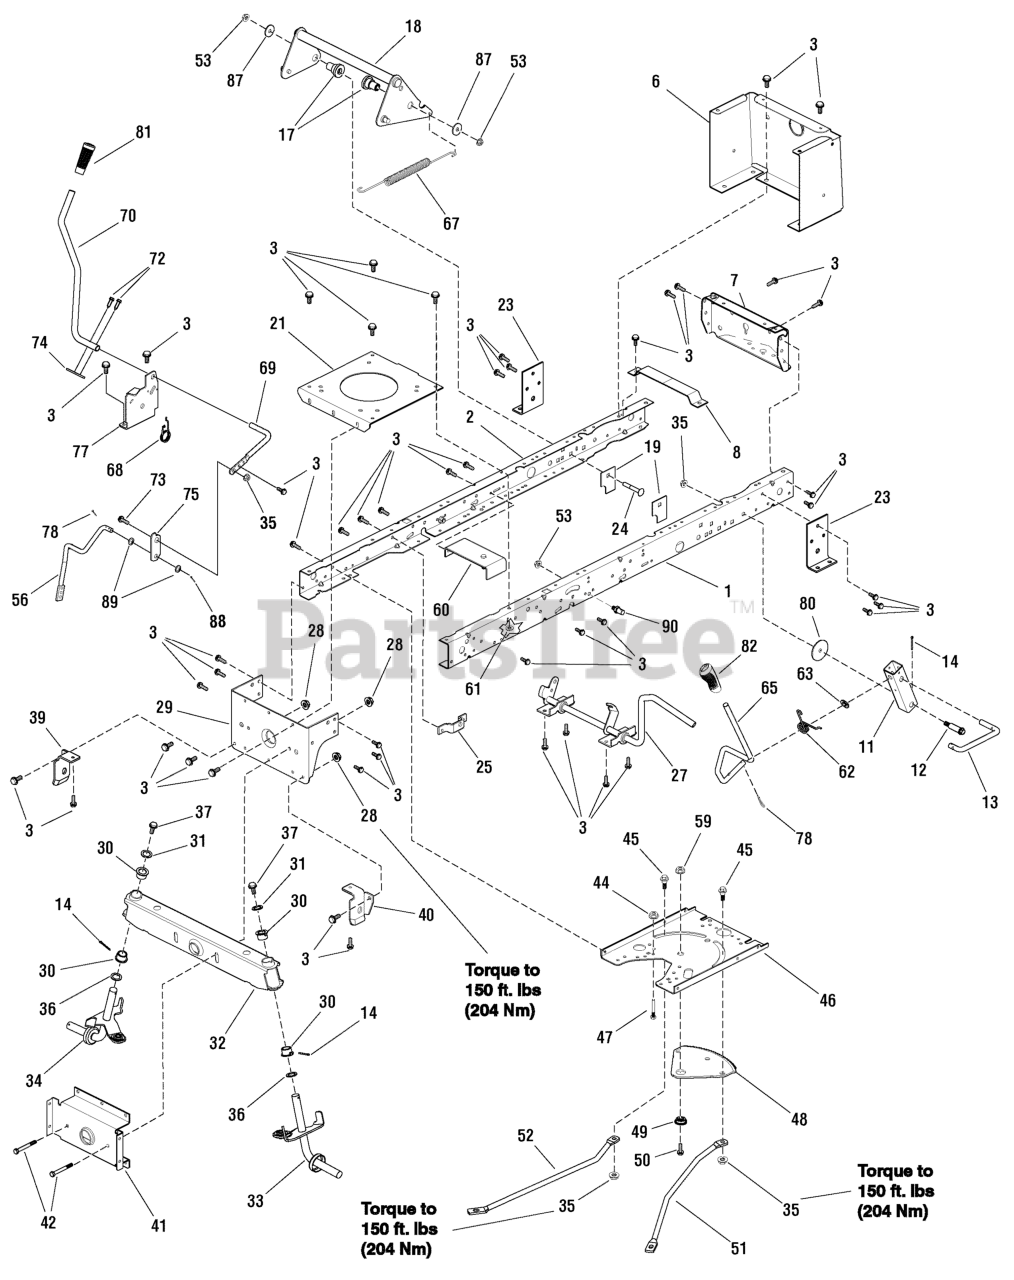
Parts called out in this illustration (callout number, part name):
1	FRAME, Left
2	FRAME, Right
3	CAPSCREW, 5/16-18 x 3/4
6	PANEL, Rear
7	PLATE, Hitch
8	BRACKET, Battery Support
11	BRACKET, Pivot
12	BOLT, Shoulder, 3/8-16 x 1/2
13	LINK, Lift Handle
14	COTTER PIN, 1/8 x 1-1/4
17	SPACER, Lifter
18	LIFTER ASSEMBLY
19	PLATE, Stiffening
21	PLATE, Engine
23	BRACKET, Transaxle
24	BOLT, Carriage, 3/8-16 x 2-1/2
25	BRACKET, Bellcrank
27	BRAKE PEDAL
28	NUT, Hex Flange, 5/16-24
29	BRACKET, Rear Hanger
30	BEARING, Spindle, LT
31	WASHER, FLAT, 25/64" ID X 1" OD X 14 GA.
33	SPINDLE, Left
34	SPINDLE, Right
35	NUT, Hex Flange 3/8-16
36	WASHER, Flat 3/8
37	BOLT, Hex 3/8-16 x 1-1/2
39	HANGER, Right Deck
40	HANGER, Left Deck
41	AXLE, Hanger
42	BOLT, Hex Head, 5/16-24 x 2-3/4
43	SECTOR GEAR ASSEMBLY
44	NUT, Hex Flange, 5/16-18
45	BOLT, Shoulder, 3/8-16 x 1
46	PLATE, Steering Mount
47	SCREW, Guide
48	GEAR, Sector
49	BEARING, Sector Gear
50	CAPSCREW, Hex Head, 5/16-18 x 1
51	DRAG LINK, Left
52	DRAG LINK, Right
53	NUT, Hex Flange, 3/8-16
56	CRANK, PTO
59	NUT, Flange, 5/16-18
61	NUT, Hex Flange, 5/16-18
62	SPRING, Torsion
63	WASHER, Flat, 1
65	HANDLE, Lift
67	SPRING, Extension
68	SPRING, Torsion, PTO
69	LEVER, PTO
70	HANDLE, PTO
72	SCREW, Thread Forming, 1/4-20 x 1
73	BOLT, Shoulder, 3/8-16 x 1/2
74	PADDLE, Switch, Yellow
75	LINK, PTO, Yellow
77	BRACKET, PTO
78	HAIRPIN
80	WASHER, Plain, 2-1/4
81	GRIP, PTO
82	GRIP, 1/2" Shaft, Tapered
87	WASHER, Flat, 1.25 x .39
88	COTTERPIN, 3/4
89	WASHER, Flat 3/4
90	PIN, Threaded Shoulder, 3/8-16 x 1-1/2
